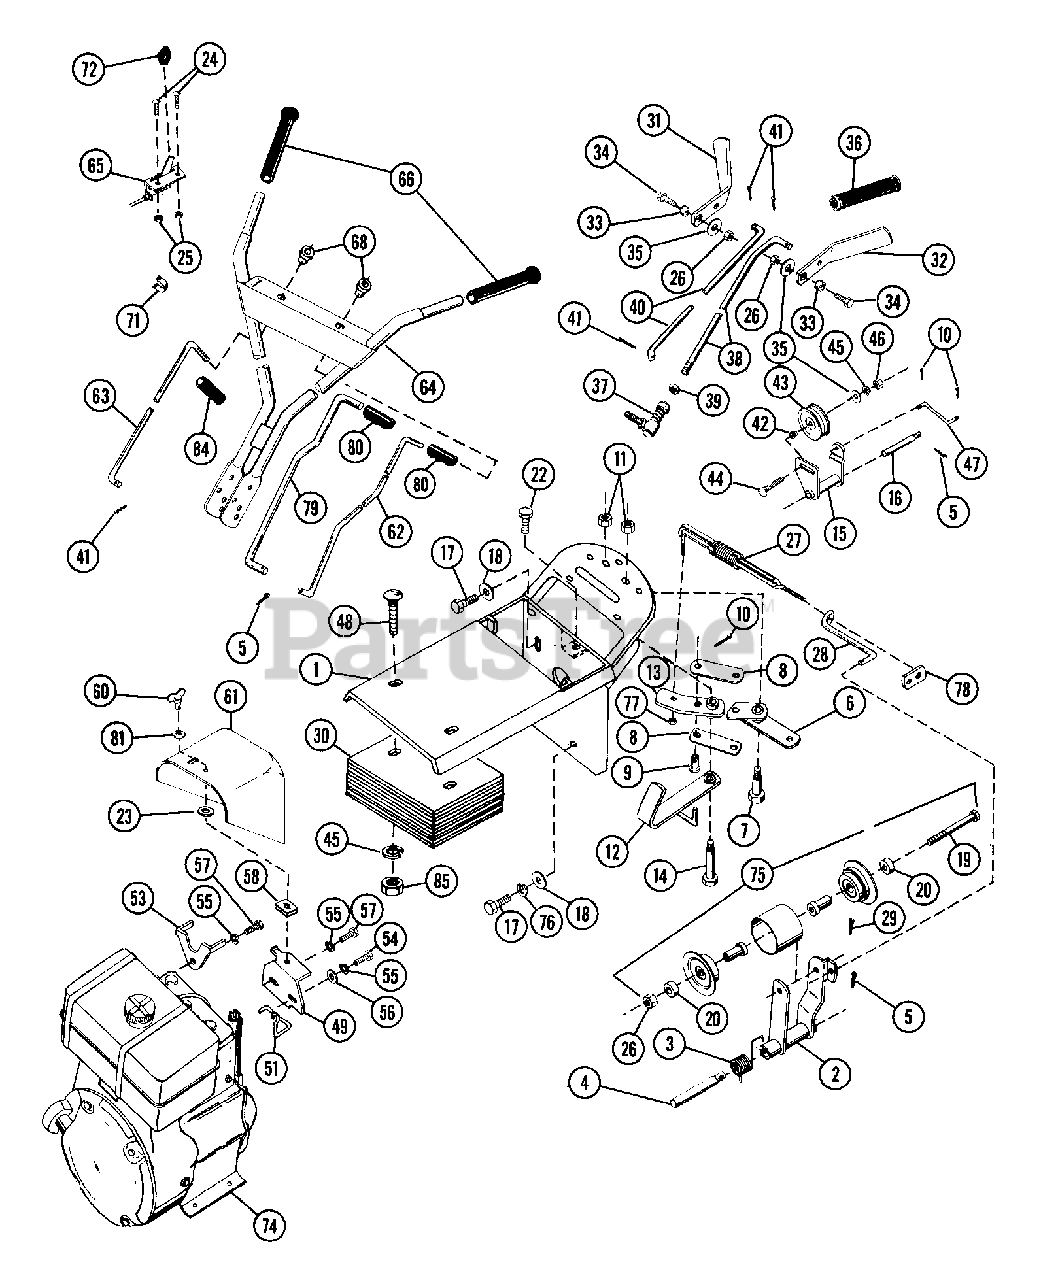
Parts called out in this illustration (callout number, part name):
2	IDLER ARM
3	SG-TORS .076X.89X1.98
4	IDLER PIN
5	PIN-COTR .12X1.0 PL
6	BELL CRANK
7	SHOULDER BOLT
9	CLEVIS PIN .243/.248X7/16
10	PIN-COTR .06X.50
11	NUT-LK-CTR .375-16 GR A PL
12	LEVER REVERSE
13	FORWARD LEVER
14	SHOULDER BOLT .50 X 1.75
15	REVERSE IDLER
16	IDLER PIN
17	BLT-HEX .38-16X1.25 PL GR 2
18	WSHR-FL-STL.406X.812X.065PL
19	BLT-HEX .31-18X2.50 PL GR2
20	BSHG, SPCR.500X.750X.321 PM
22	BLT-HEX .31-18X1.00 PL GR 2
23	NUT-RETNR
24	SCR-MCH 10-24X.50 SLRH PL
25	NUT-KEPS 10-24 PL
26	NUT-LK .312-18 GR A PL
27	CLUTCH SPRING
28	CLUTCH LINK
29	PIN-HAIR INT .06X.18X.77
30	WEIGHT WAFER
31	DRIVE CLUTCH HANDLE
32	TILLER CLUTCH HANDLE
33	SPACER BUSHING .5 X .32 X .21
34	BLT-HEX .31-18X.75 PL GR2
35	WSHR-FL-STL .38X.875X.083 PL
37	SNAP IN BALL JOINT
38	TILLER CLUTCH ROD
39	NUT-HEX .312-24 PL
40	DRIVE CLUTCH ROD
41	PIN-COTR .09X.75 PL
42	SPCR, BRG .315X.50X.688X.281
43	IDLER
44	BLT-RDHDSQNK .31-18X1.38SHT PL
45	WSHR-LK .375X.094 MED PL
46	NUT-HEX .312-18
47	LINK REVERSE
48	BLT-RDHDSQNK .38-16X2.25 SHTPL
49	BELT COVER BRACKET
51	BELT FINGER
51	FORWARD BELT FINGER
53	BELT FINGER
54	BLT-HEX .31-24X.75 PL GR5
55	WSHR-LK-INT .313X.030 PL
56	WSHR-FL-STL .323X.625X.062 PL
57	BLT-HEX .31-24X.50 GR5
58	NUT-SPEED 1/4 TURN SOUTHCO
60	SCR-WING .25 TURN SOUTHCO
61	BELT COVER
62	CLUTCH ROD
63	HANDLEBAR
64	HANDLEBAR
65	THROTTLE CONTROL
66	HANDLEGRIP
68	SNAP BUSHING
71	CABLE RETAINER
72	HANDLE GRIP
73	BLT-HEX .25-20X.75 PL GR2
75	IDLER ASSEMBLY
76	WSHR-LK .375X.115 HVY PL
77	NUT-LK 8-32 GR A PL
78	RETAINING NUT
79	WMT, IDLER MOUNT(COMM.BAGGER)
80	GRIP
81	WSHR-FL-STL .250X.562X.049 PL
84	NUT-HEX .375-16
85	GRIP
